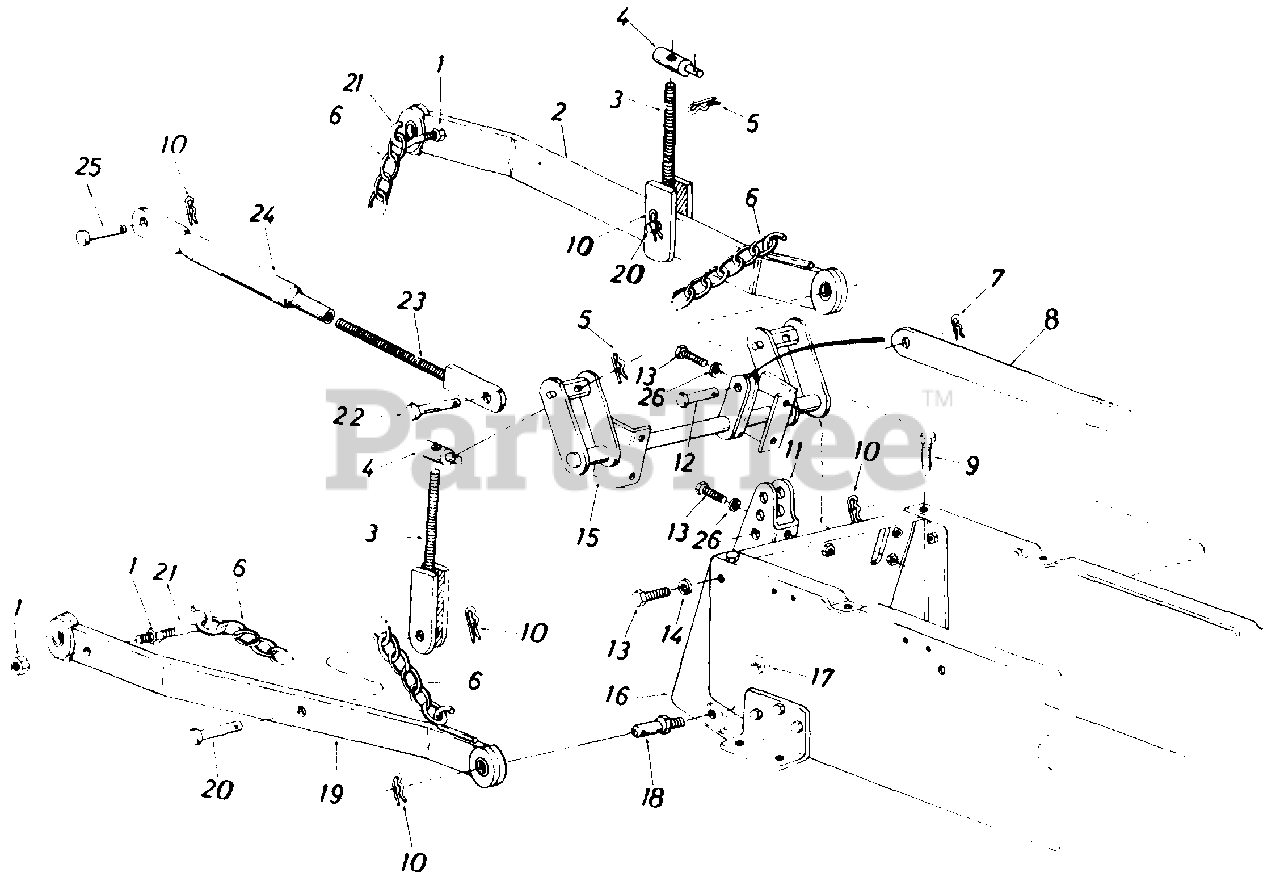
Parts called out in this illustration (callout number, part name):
1	Hex Cent. L-Nut 7/16-14 Thd.
2	Draft Bar Ass'y.- L.H.
3	Clevis Screw Ass'y.
4	Clevis Pin
5	Hitch Pin Clip
6	Chain - 20 Links
7	Cotter Pin 1/8" Dia. x 1.25" Lg
10	Hairpin Cotter
12	Clevis Pin
13	Hex Scr. 3/8-16 x .75" Lg.
14	L-Wash. 3/8" Scr.- H.D.
18	Link Clevis Pin
19	Draft Bar Ass'y.- R.H.
20	Clevis Pin .63" Dia. x 1.66" Lg.
21	Hitch Chain Hook
22	Clevis Pin .63" Dia. x 2.4" Lg.
23	Clevis Screw
25	Clevis Pin .63" Dia. x 2.4" Lg.
26	L-Wash. 3/8" Scr.- H.D.
13196-0648	PLATE-HITCH - TECH GRAY (0648)
13196-0665	PLATE-HITCH - YARDMAN GREEN (0665)
